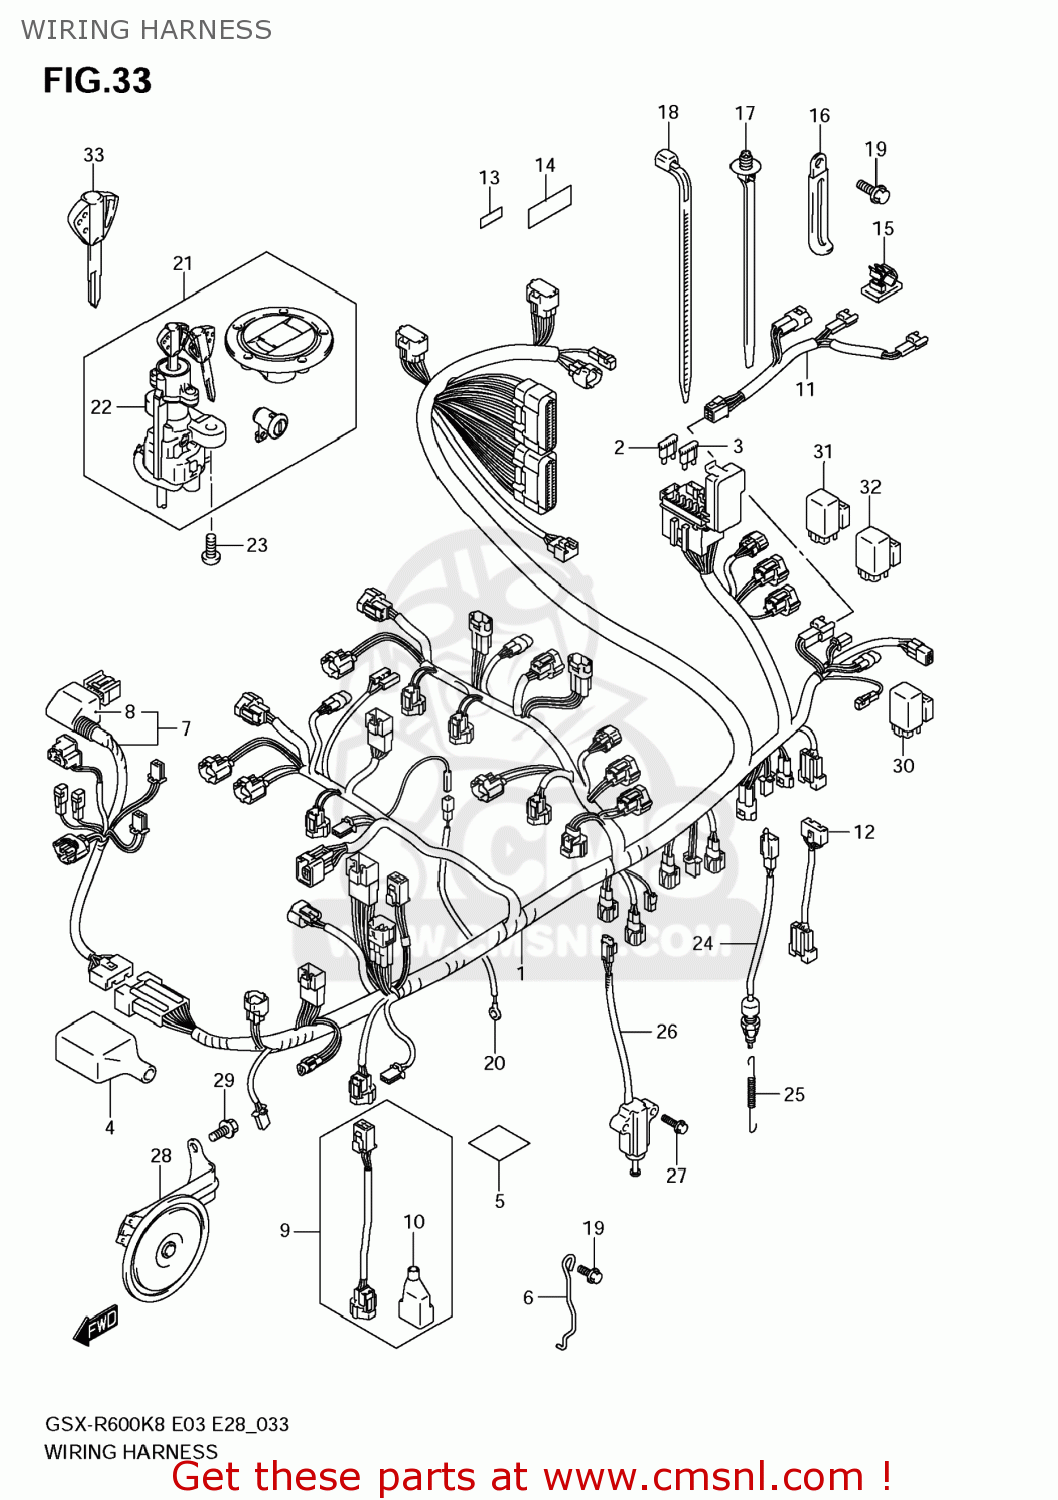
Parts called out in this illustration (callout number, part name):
1	HARNESS,WIRING NO.1
2	FUSE(10A)
3	FUSE(15A)
4	COVER
5	PROTECTOR(30X80X1)
6	GUIDE,WIRING HARNESS
7	HARNESS,WIRING NO.2
8	COVER,CONNECTOR
9	WIRE,ACTUATOR LEAD
10	COVER,SUB THROTTLE ACTUATOR
11	WIRE,RR COMB
12	WIRE,RELAY LEAD
13	PROTECTOR,WIRING HARNESS
14	PROTECTOR,WIRING HARNESS
15	CLAMP
16	CLAMP(L:45)
17	CLAMP(L:154)
18	CLAMP(L:125)
19	BOLT
20	WIRE,OIL PRESSURE SWITCH LEAD
21	LOCK SET
22	LOCK ASSY,STEE
23	BOLT(8X20)
24	SWITCH ASSY,STOP LAMP
25	SPRING
26	SWITCH ASSY,SIDE STAND
27	BOLT
28	HORN ASSY
29	BOLT
30	RELAY ASSY
31	RELAY ASSY
32	RELAY ASSY,HEADLAMP
33	KEY,BLANK(IMMOBII)
